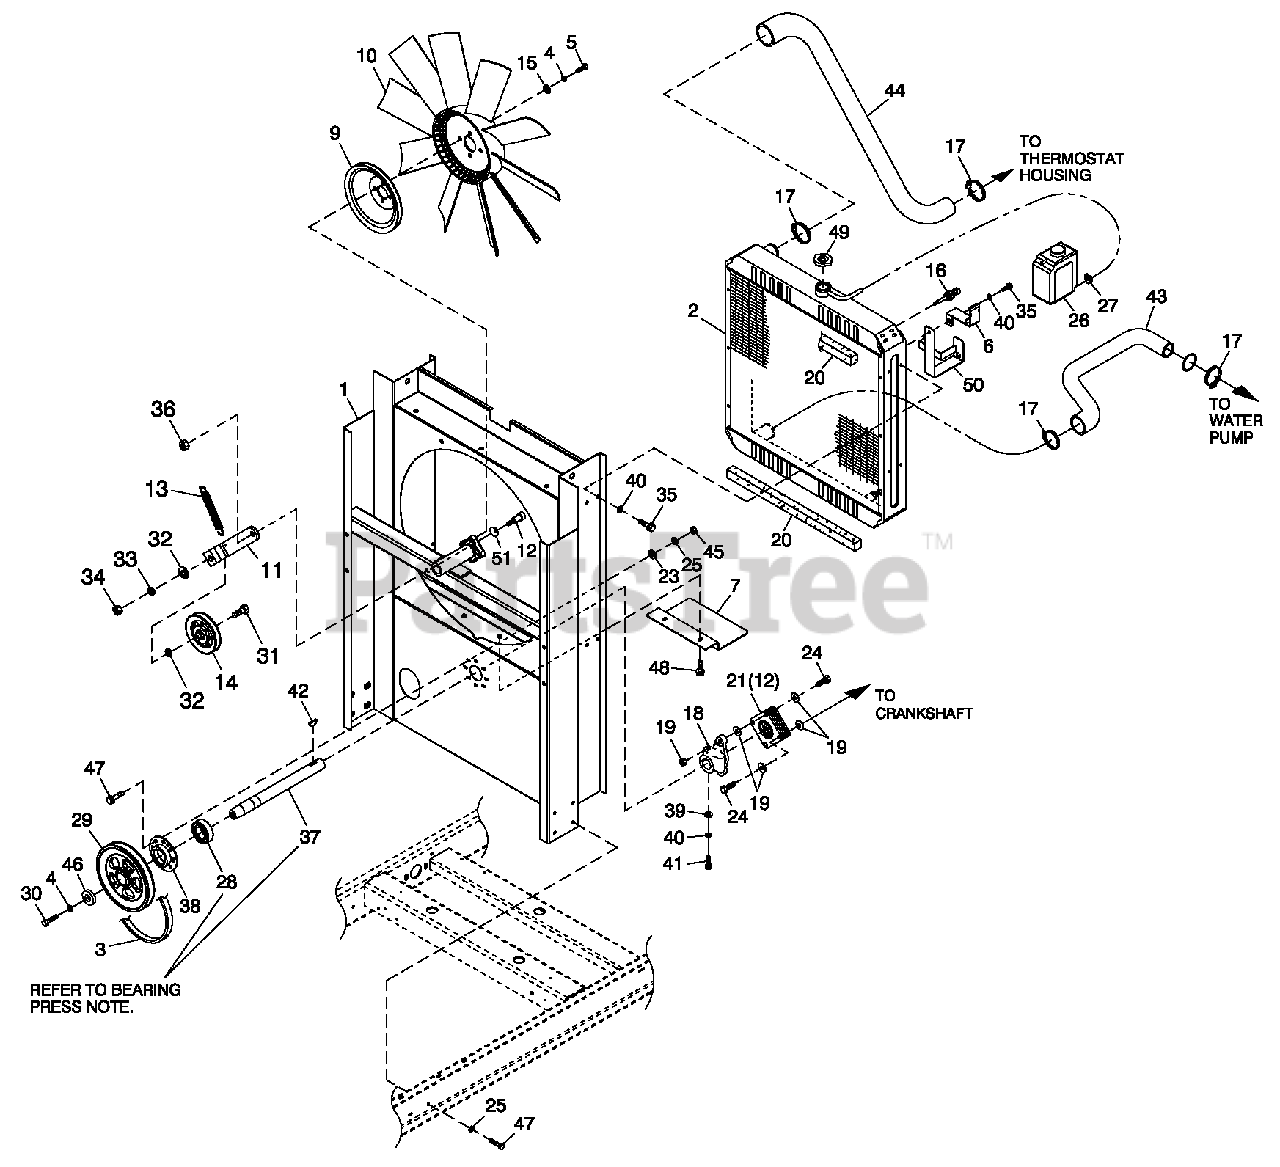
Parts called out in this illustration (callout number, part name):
1	WELDMENT RADIATOR SUPPORT 2.4L
2	RADIATOR 598 X 568 X 49 CPL RH
3	V-BELT 31/64" X 57-3/8"
4	WASHER LOCK M10
5	SCREW HHC M10-1.5 X 30 G10.9
6	BRACKET, SIGNAL CONDITIONER (USED ONLY WITH QTA PRODUCT)
7	SHIELD RADIATOR C4
9	PULLEY FAN V-GROOVE 9"
10	FAN COOL 22" DIA 10 BLADE LH
11	ARM TENSIONER
12	SHOULDER BOLT 3/8 X 1/2"
13	SPRING TENSION CPL
14	PULLEY V-BELT 4" FLANGED
15	WASHER FLAT 3/8-M10 ZINC
16	PROBE COOLANT LEVEL 3/8 NPTF
17	CLAMP HOSE #28 1.32-2.25
18	HUB FLEX PLATE
19	WASHER FLEX (THIN)
20	TAPE FOAM 1 X 1 (26.75" LG)
21	DISK FLEX
23	WASHER FLAT 1/4-M6 ZINC
24	SCREW HHC 5/16-24 X 1-1/4 G5
25	WASHER LOCK M6-1/4
26	TANK COOLANT RECOVERY
27	CLAMP HOSE BAND 1/4
28	BEARING #6205 2NSE C3 E SRI2 S
29	PULLEY 4.5" DIA MACHINED
30	SCREW HHC M10-1.5 X 30 G8.8
31	SCREW HHC 1/2-13 X 2" G8
32	WASHER FLAT 1/2 ZINC
33	WASHER LOCK 1/2
34	NUT HEX 1/2-13 STEEL
35	SCREW HHFC M8-1.25 X 20 W/M6
36	NUT HEX LOCK 5/16-18 NY INS SS
37	SHAFT FAN DRIVE
38	RETAINER BEARING
39	WASHER FLAT 5/16-M8 ZINC
40	WASHER LOCK M8-5/16
41	SCREW HHC M8-1.25 X 35 G8.8
42	KEY WOODRUFF 4 X 19D
43	HOSE LOWER RADIATOR G2
44	HOSE UPPER RADIATOR G2
45	NUT HEX M6 X 1.0 G8 YEL CHR
46	SPACER .5 X 1.5 X .25 STL/ZINC
47	SCREW HHFC M6-1.0 X 20 G8.8
48	SCREW THF M6-1 X 16 N WA Z/JS
49	CAP RADIATOR 13 PSI
50	BRACKET COOLANT TANK
51	WASHER BELLEVILLE .75X.38X.028
